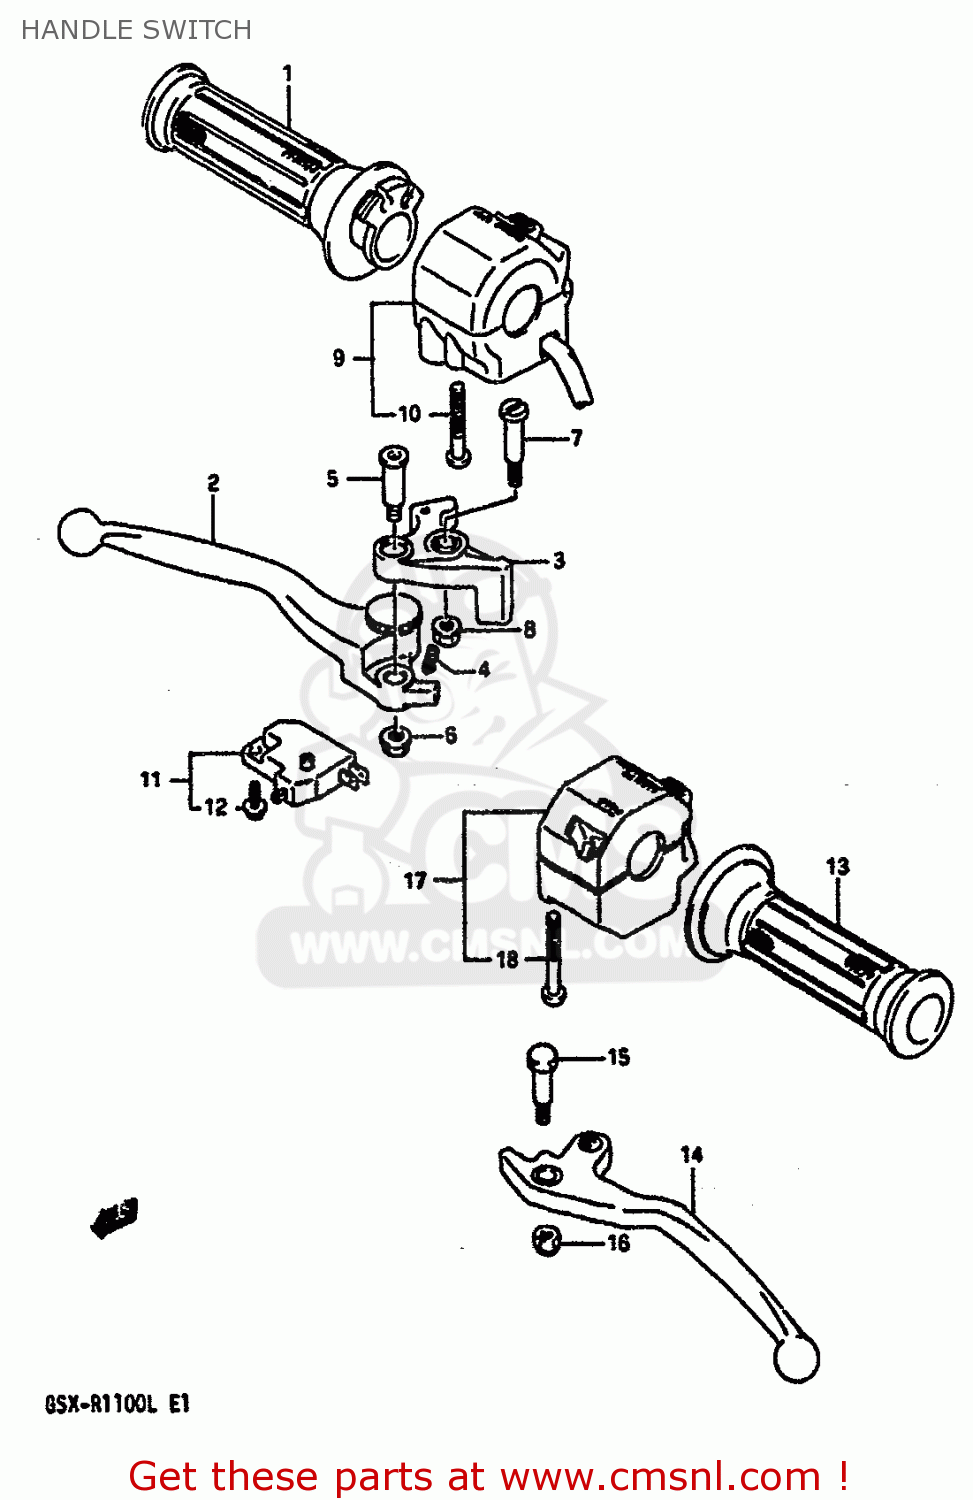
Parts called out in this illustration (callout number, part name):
1	GRIP,THROTTLE
2	LEVER,ADJUST
3	KNOCKER
4	SPRING
5	BOLT,LEVER
6	NUT
7	BOLT,LEVER PIVOT
8	NUT 6MM
9	SWITCH ASSY,HANDLE RH
10	SCREW, 5X45
11	SWITCH ASSEMBLY,STOP
12	SCREW
13	GRIP,L
14	LEVER,CLUTCH (SILVER)
15	BOLT,LEVER
16	NUT
17	SWITCH ASSY,HANDLE LH
18	SCREW, 5X45
